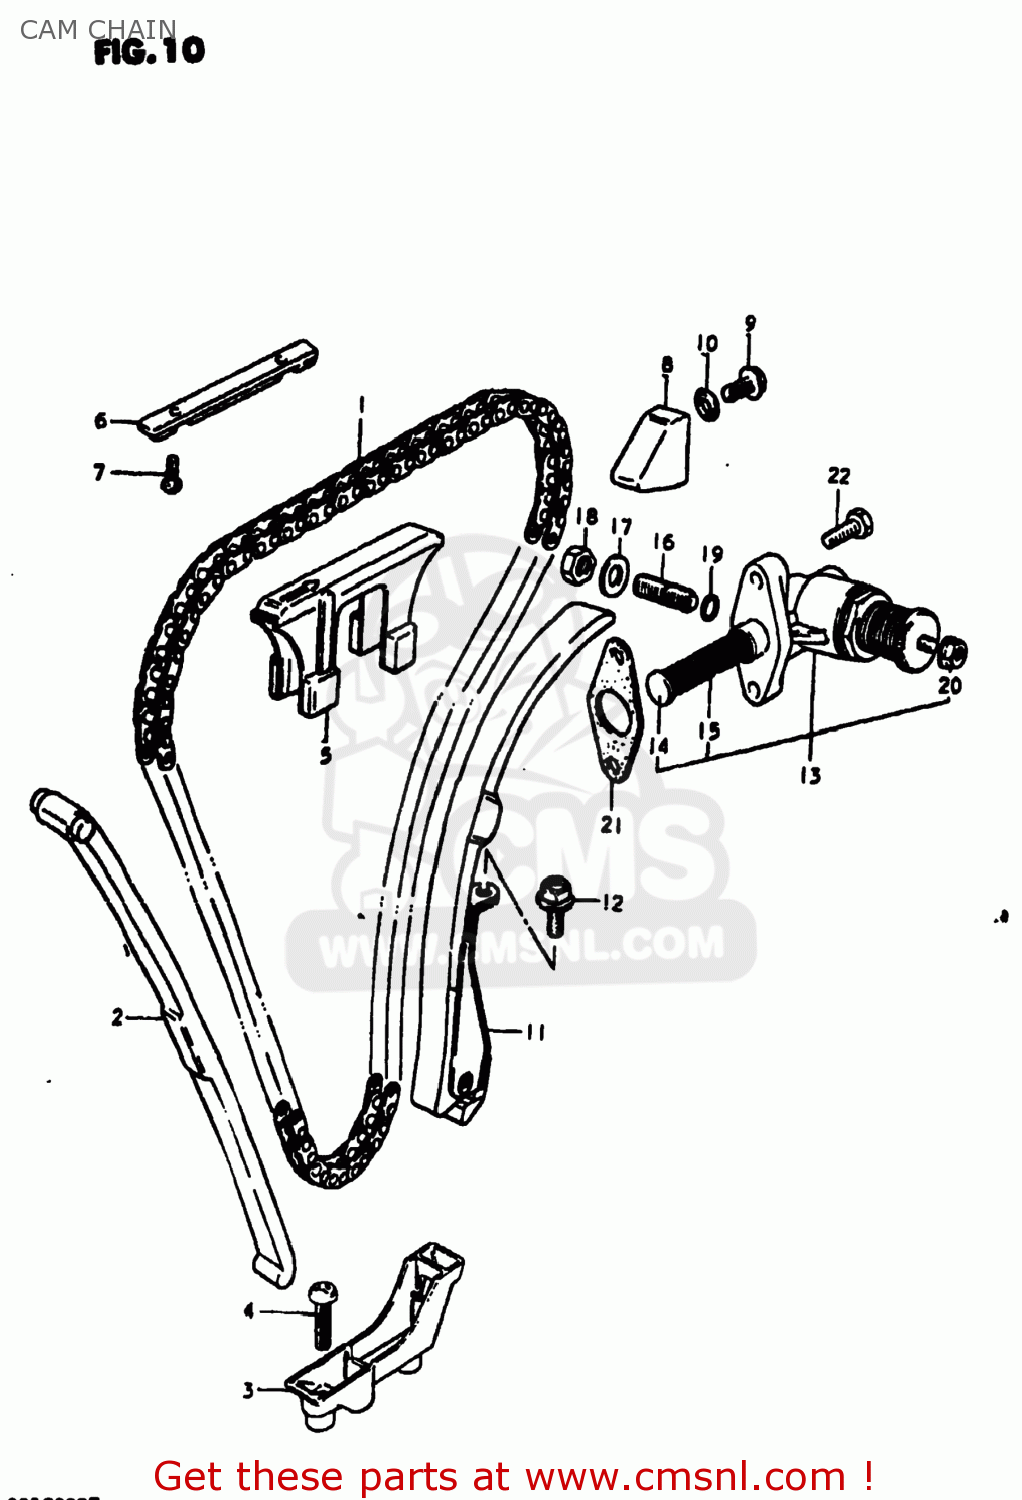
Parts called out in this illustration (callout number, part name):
1	CHAIN,CAMSHAFT DRIVE
2	GUIDE,CAM CHAIN NO.1
3	HOLDER,CAM CHAIN GUIDE
4	SCREW
5	GUIDE,CAM CHAIN NO.2
6	GUIDE,CAM CHAIN
7	SCREW
8	GUIDE,CAM CHAIN
9	BOLT
10	GASKET (NAS)
11	TENSIONER,CAM CHAIN
12	BOLT
13	ADJUSTER ASSEMBLY,TENSIONER
14	ROD,PUSH
15	SPRING
16	SCREW
17	WASHER
18	NUT
19	O-RING
20	NUT
21	GASKET,TENSIONER ADJUSTER (MCA)
22	SCREW (6X25)
